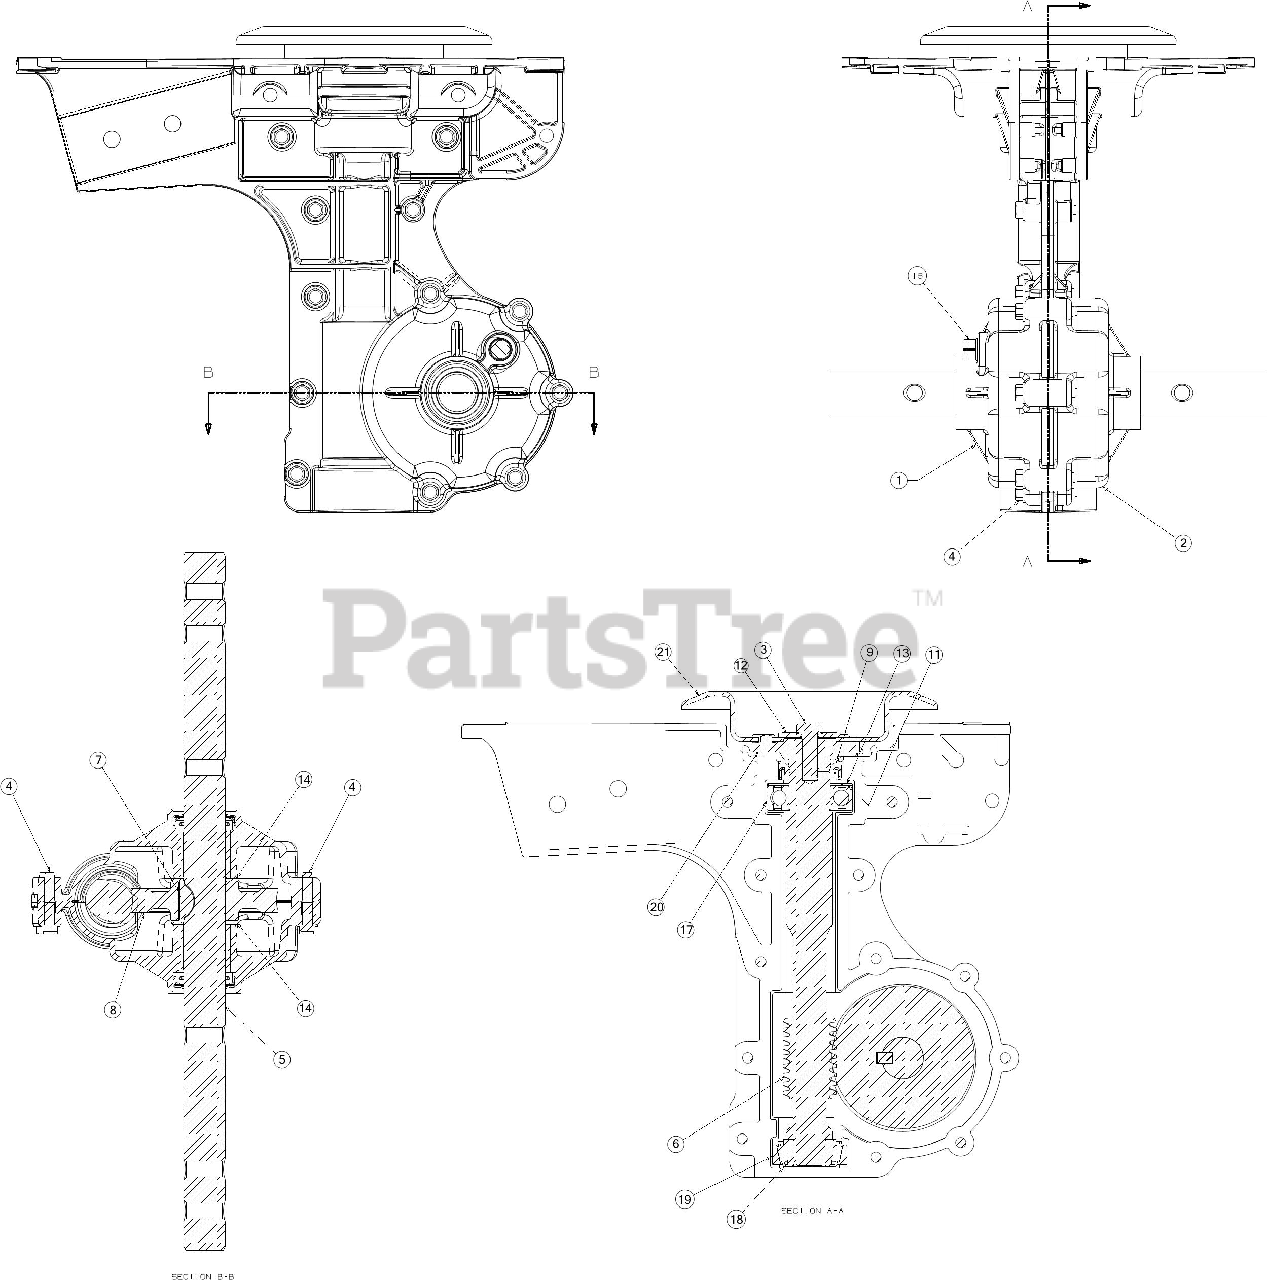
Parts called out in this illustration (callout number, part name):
3	SCREW 3/8-24 X 1.00 GR5
4	SCREW 1/4-20 X 1.25
7	KEY-HI-PRO #A-1/4
9	OIL SEAL
11	FLAT WASHER
13	FLAT WASHER 1.50
14	WASHER 1.010X1.560X.060
16	PIPE PLUG 1/4-18
17	BALL BEARING
18	BEARING CONE
19	BEARING CUP
20	PULLEY ADAPTER
21	PULLEY
